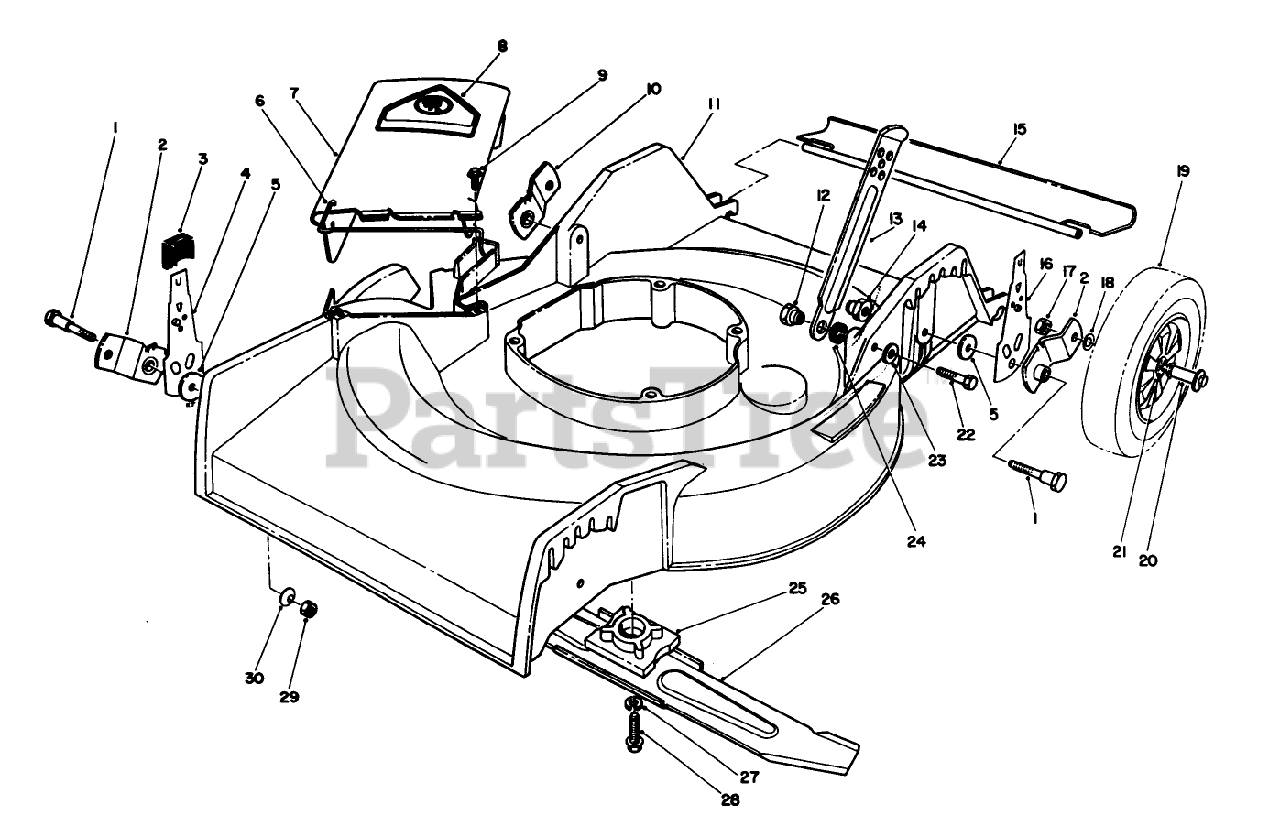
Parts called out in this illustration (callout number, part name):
1	5/16-18 PIVOT SCREW
3	KNOB-ARM
4	RH FRONT SPRING ARM ASM
5	PIVOT WASHER
8	DECAL-DANGER
9	SCREW-HWH
12	HANDLE PIVOT NUT
13	HANDLE LATCH
14	HANDLE PIVOT NUT
16	REAR SPRING ARM ASM
18	WASHER
19	WHEEL TIRE ASM 8 IN
20	BOLT-WHEEL
21	BUSHING
22	SCREW-HH
23	WASHER-LOCK
24	SPACER
25	BLADE RETAINER
27	WASHER-LOCK
28	SCREW-HH
29	NUT-LOCK, NI
30	WASHER-BELLEVILLE
